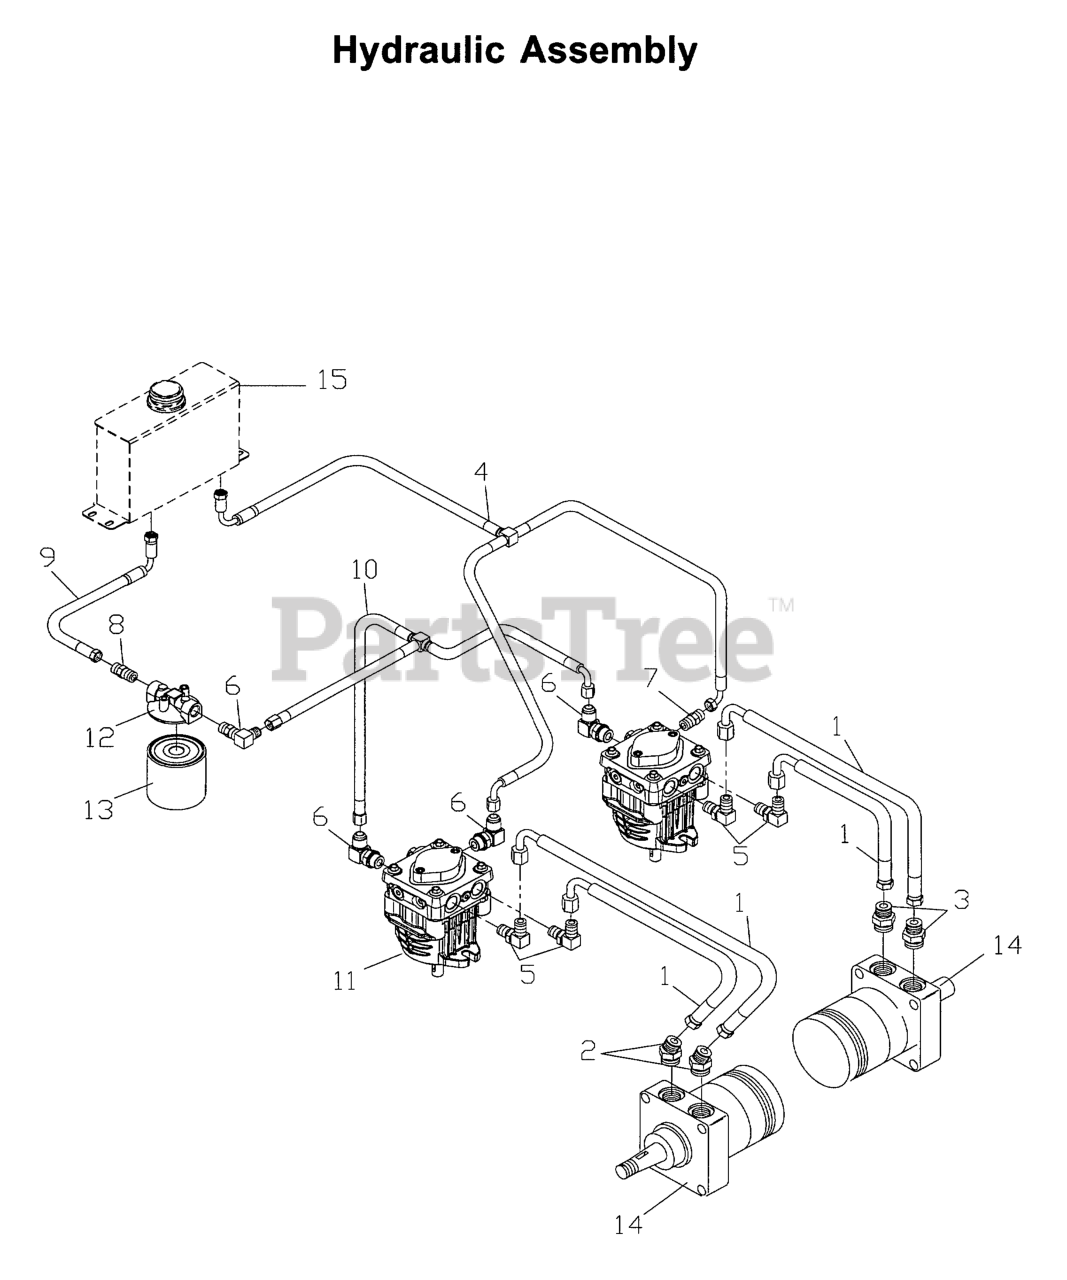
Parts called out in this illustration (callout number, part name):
1	HOSE, 1/2" HYDRAULIC
2	ELBOW-ADJ 45 DEG F6802-8-10
3	CONNECTOR, STRAIGHT
4	INLET TEE HOSE
5	ELBOW, 90 DEGREE
6	ELBOW, F6801-6-6-0 90 DEGREE
7	FITTING, STRAIGHT F6400-6-4-0
8	STRAIGHT FITG
9	HOSE
10	RETURN TEE HOSE
11	HG_PUMP
12	FILTER HEAD
13	HYDRAULIC OIL FILTER
14	WHEEL MOTOR
15	OIL TANK BLK
539103664	SEAL KIT - GEN I
